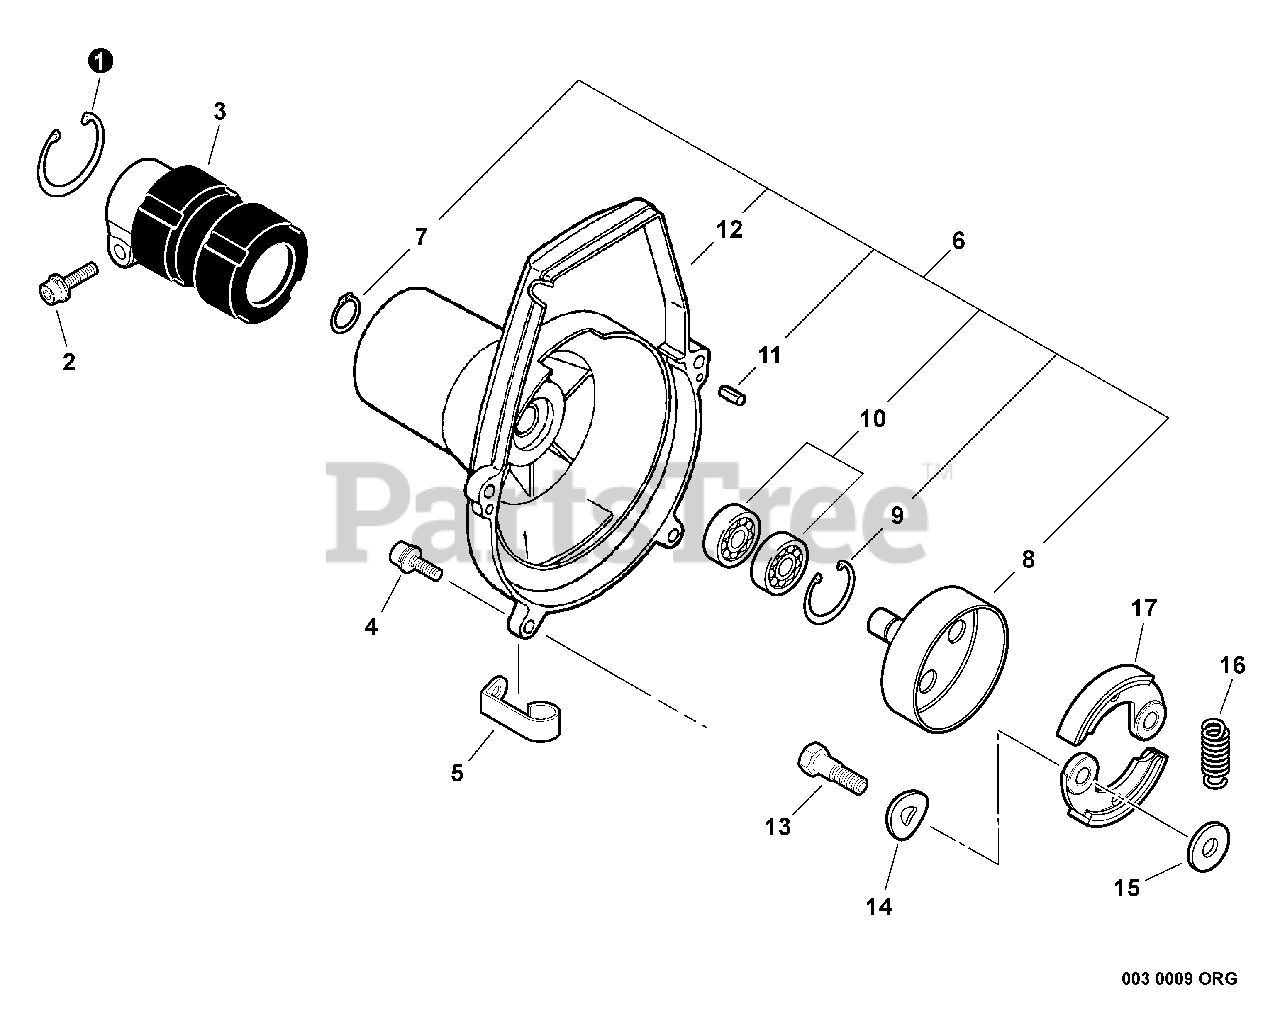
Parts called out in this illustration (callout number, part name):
1	RING, SNAP Ø42
2	BOLT 5×28
3	HOLDER, MAIN PIPE
4	BOLT 5×18
6	COVER ASSY, FAN - ORANGE
7	RING, RETAINING - 12
8	DRUM, CLUTCH
9	RING, SNAP 28
10	BEARING, BALL 6001
11	PIN, LOCATING 4
12	COVER, FAN
13	BOLT, CLUTCH 8×7.9×M6
14	WASHER, SPRING 8.5×16×0.5
15	WASHER 6.2×19×1.0
16	SPRING, CLUTCH
17	SHOE, CLUTCH
